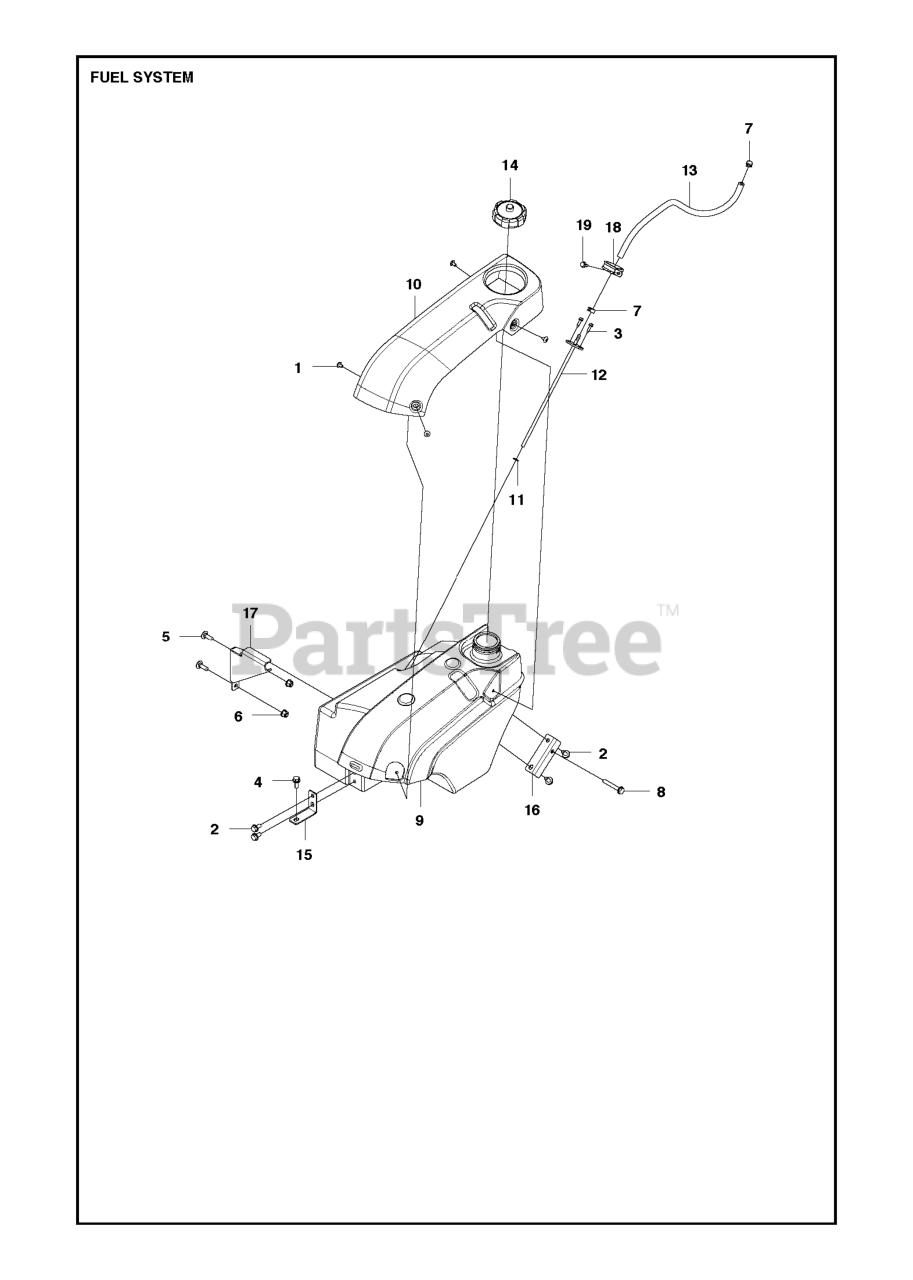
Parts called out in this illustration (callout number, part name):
6	NUT FLANGE
8	SCREW EHHFM
18	HOSE CLAMP
19	SCREW
